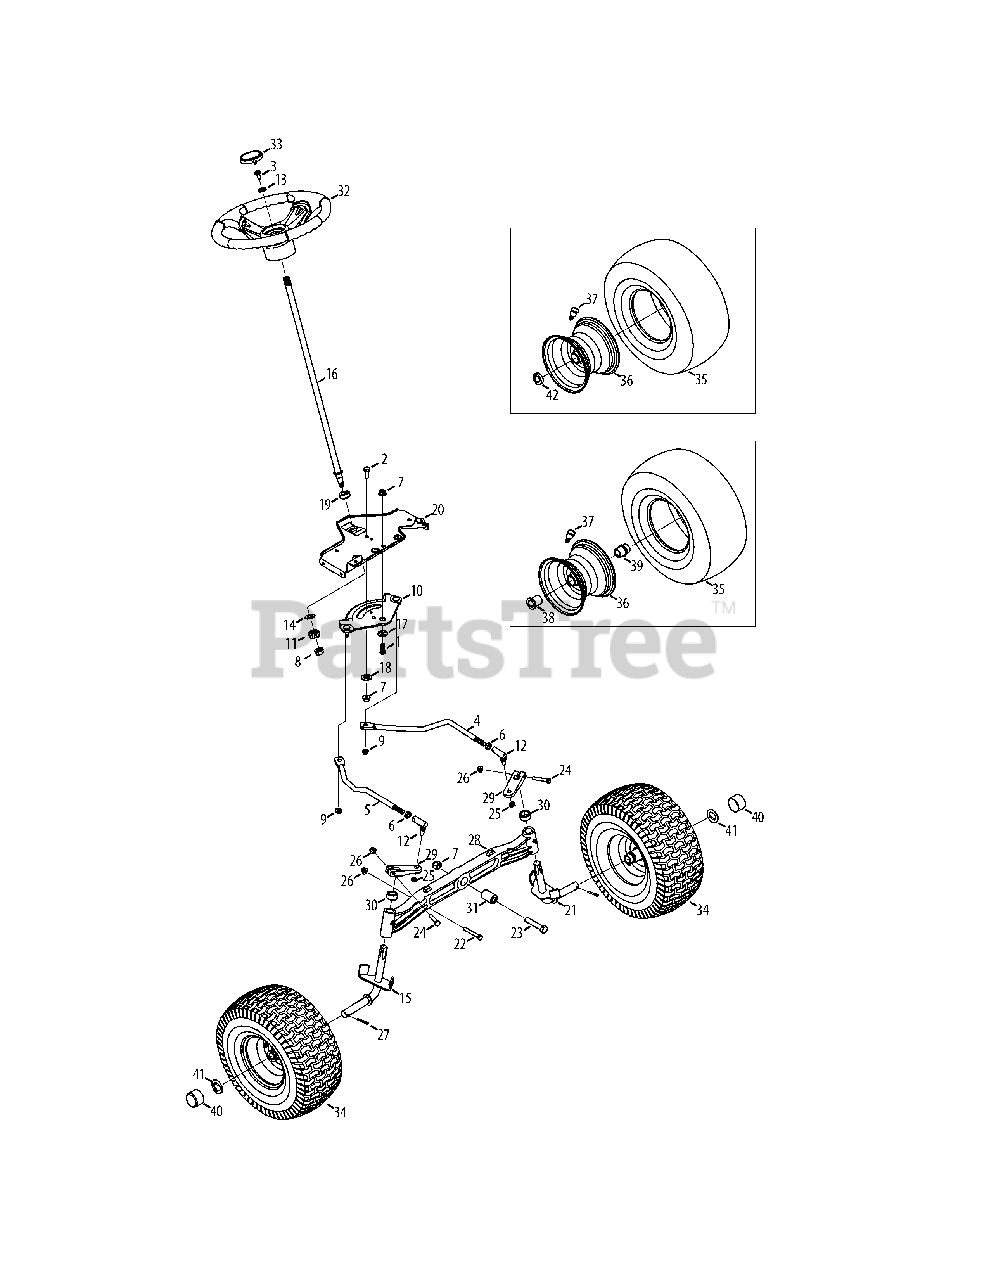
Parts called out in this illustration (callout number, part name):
1	Hex Screw, 3/8-16, 1.00, Gr5, Spec
2	Hex Screw, 3/8-16, 1.00, Gr5, Std
3	Hex Screw, 5/16-18, 1.00, Gr5, Lock
4	Link, Drag LH
5	Link, Drag RH
6	Nut, Jam, 7/16-20, Gr2
7	Nut, Flange Lock, 3/8-16, Grf,
8	Nut, Flange Lock, 7/16-20, Grb, Lock
9	Nut, Flange Lock, 5/16-18, Gr5, Sd Lk
10	Gear, Steering, 11/90 Ratio
11	Gear, Pinion, Steering
12	Ball Joint, 7/16-20, Lock
13	Washer, Flat, .406 x .875 x .105
14	Washer, Flat, .51 x 1.12 x .06
15	Axle Ass’y, RH .750 Dia (46" Deck)
16	Shaft, Steering, .625 OD x 24.25
17	Spacer, Shoulder, .385x 1.25 x .3025
18	Spacer, .38 x 1.375, Special, 46" Only
19	Bearing, Flange, Hex 5/8 Pm
20	Bracket, Support, Steering
20	Screw, .750 5/16-18
21	Axle Ass’y, LH .750 Dia (46" Deck)
22	Hex Screw, 5/16-18, 2.25, Gr5, Std
23	Hex Screw, 3/8-16, 2.50, Gr5, Std
24	Hex Screw, 5/16-18, 1.75, Gr5, Std
25	Nut, Hex Lock, 3/8-24, Grb
26	Nut, Flange Lock, 5/16-18, Grf
27	Pin, Cotter, 5/32, 1.25
28	Axle, Pivot Bar, Cast
29	Steering, Block
30	Spacer, .71 ID x .125 OD x .56
31	Spacer, .385 x 1.00 x 1.5075
32	Steering Wheel, Standard Grip
33	Cap, Sprig, Small
34	Wheel Assembly
35	Tire, 15 x 6 x 6
36	Rim Assembly, w/Flange Bearing, 46"
37	Tubeless Air Valve
38	Flange Bearing, .760 x 1.00 x 1.20
39	Flange Bearing, .760 ID
40	Cap, Bumper, 46"
41	Washer, Flat, .350 x 1.559 x .062, 46"
42	Bearing, Ball, .750 x 1.750, 38" & 42"
